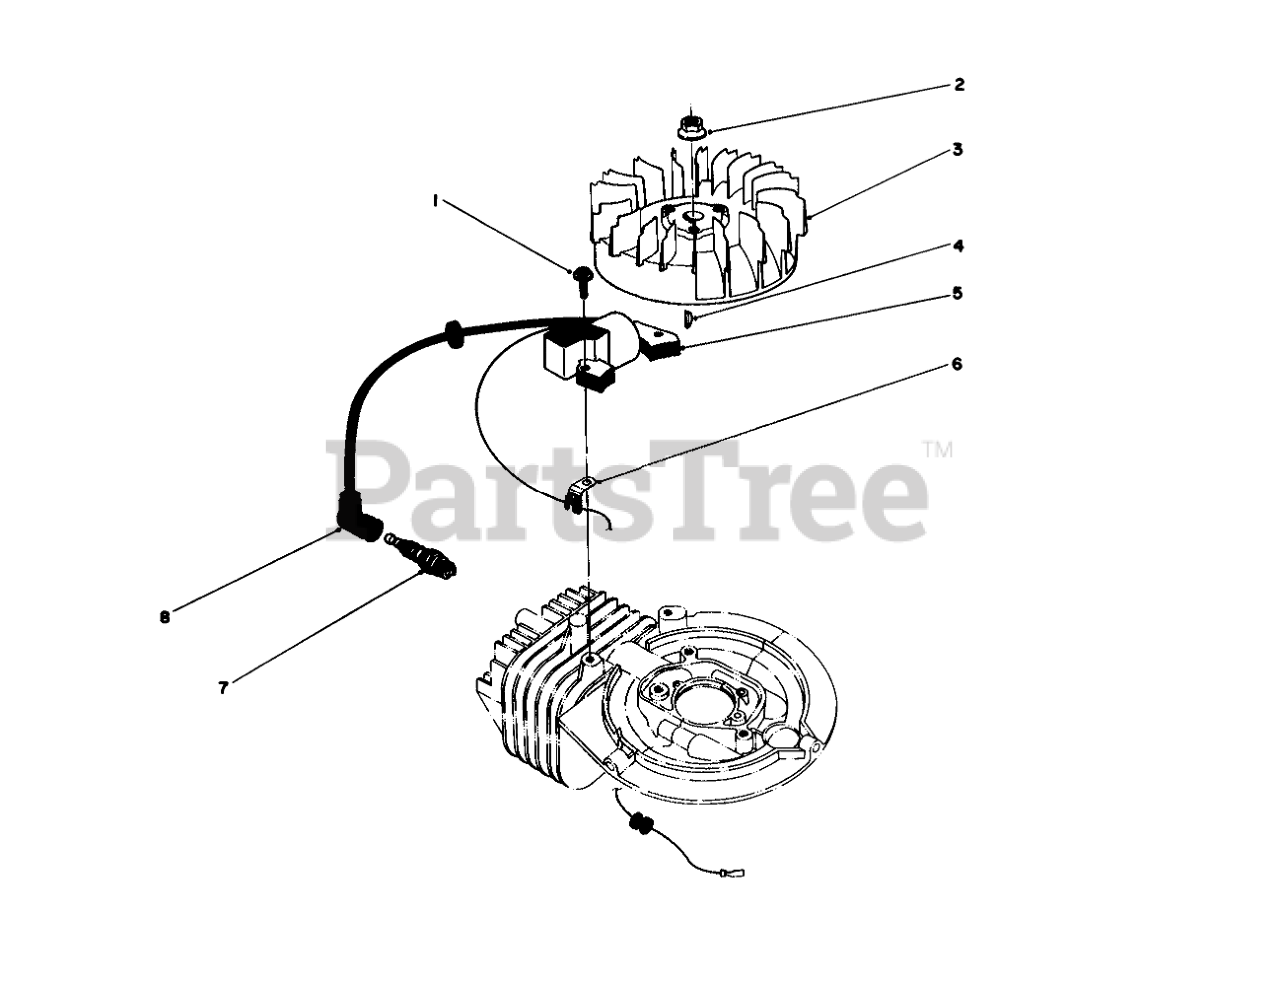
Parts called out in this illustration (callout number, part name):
1	Allenhead
3	FLYWHEEL
5	Coil/Ignition Assembly
6	CLAMP
7	Sparkplug
8	CAP-SPARKPLUG
